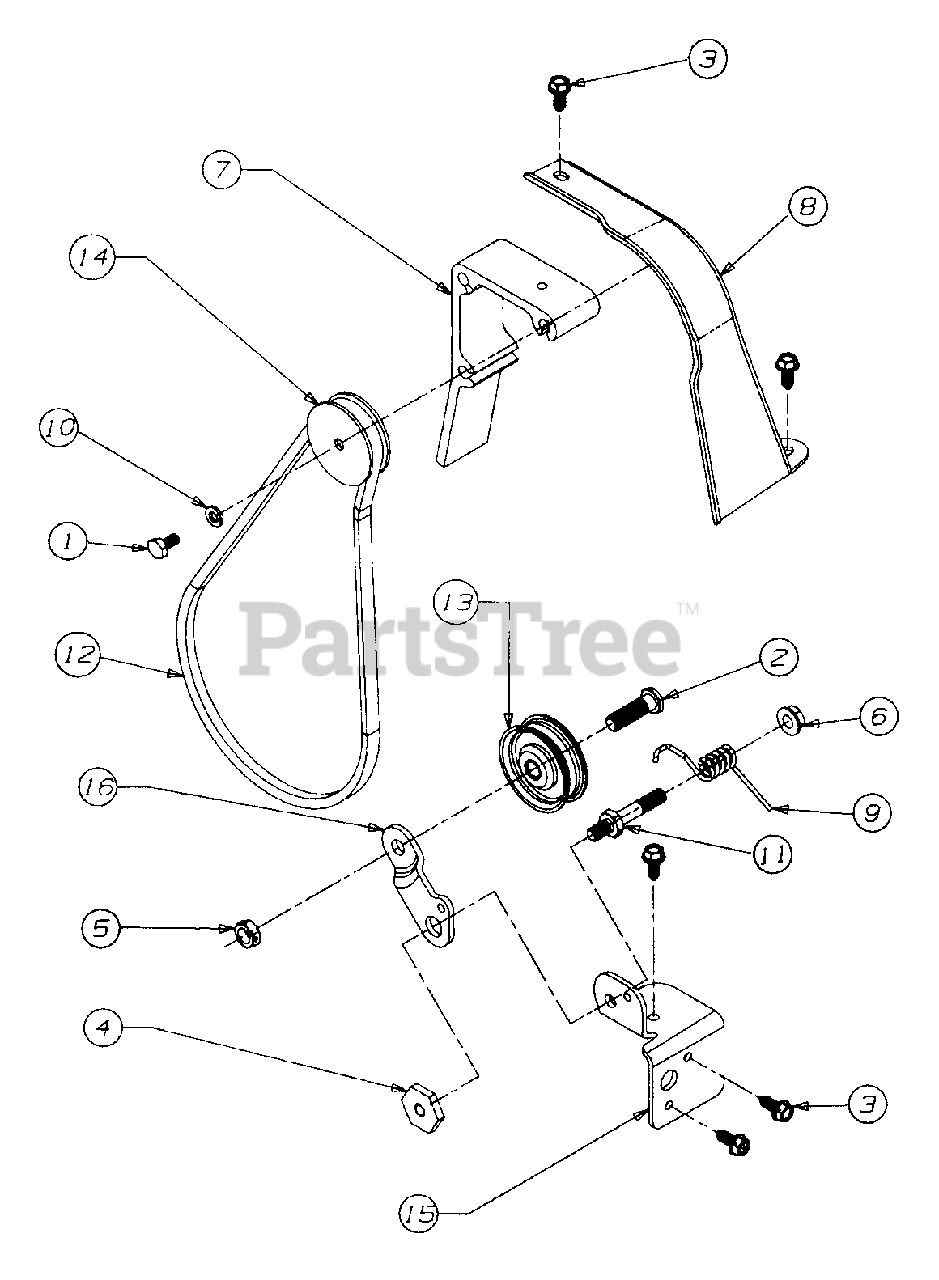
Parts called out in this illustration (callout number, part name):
4	NUT - HEX SHOULDER
5	NUT - HEX LOCK
6	NUT - HEX LOCK FLANGE
7	ADAPTER - MOUNTING
10	WASHER - LOCK
11	BOLT - IDLER
12	V-BELT
13	IDLER - FLAT
